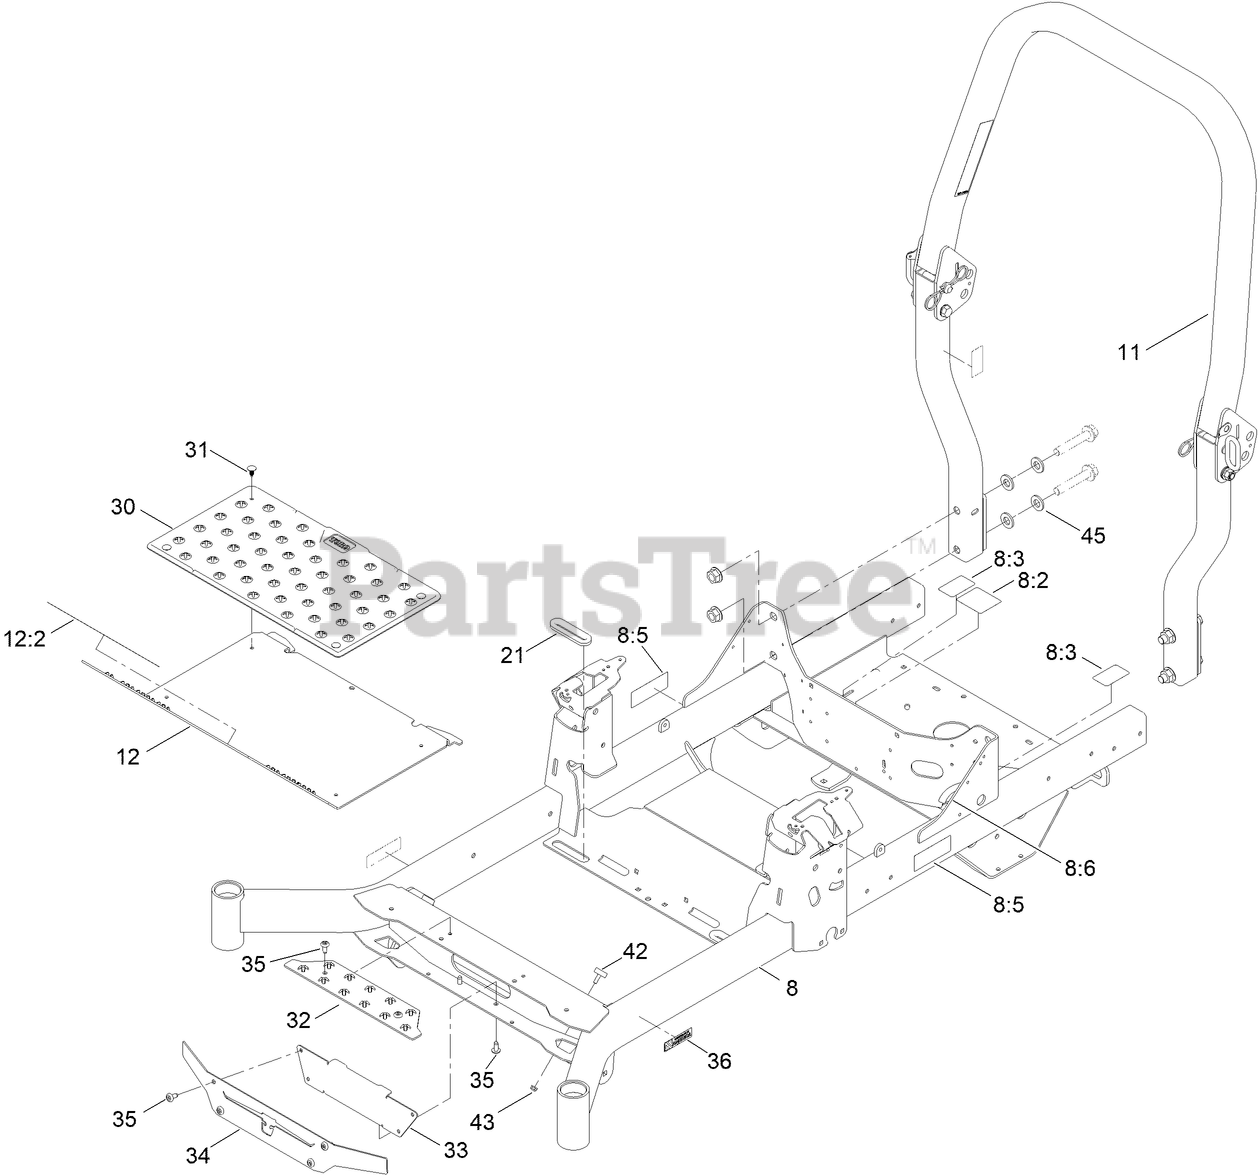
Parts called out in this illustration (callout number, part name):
8	FRAME-60
8:2	DECAL-ROUTING, BELT
8:3	DECAL-RELEASE, DRIVE
8:5	DECAL-WARNING
8:6	STRIP-SEAL
11	ASM-ROPS
12	PAN-FLOOR ASM
12:2	DECAL-DANGER
21	GROMMET-RUBBER
30	MAT-FLOOR
31	PLUG-PLASTIC
32	PLATE-STEP
33	PLATE-BACKER
34	PLATE-FASCIA
42	BUMPER-RUBBER
43	NUT-HF
45	WASHER,5/8 FLAT HARDEN YZN
